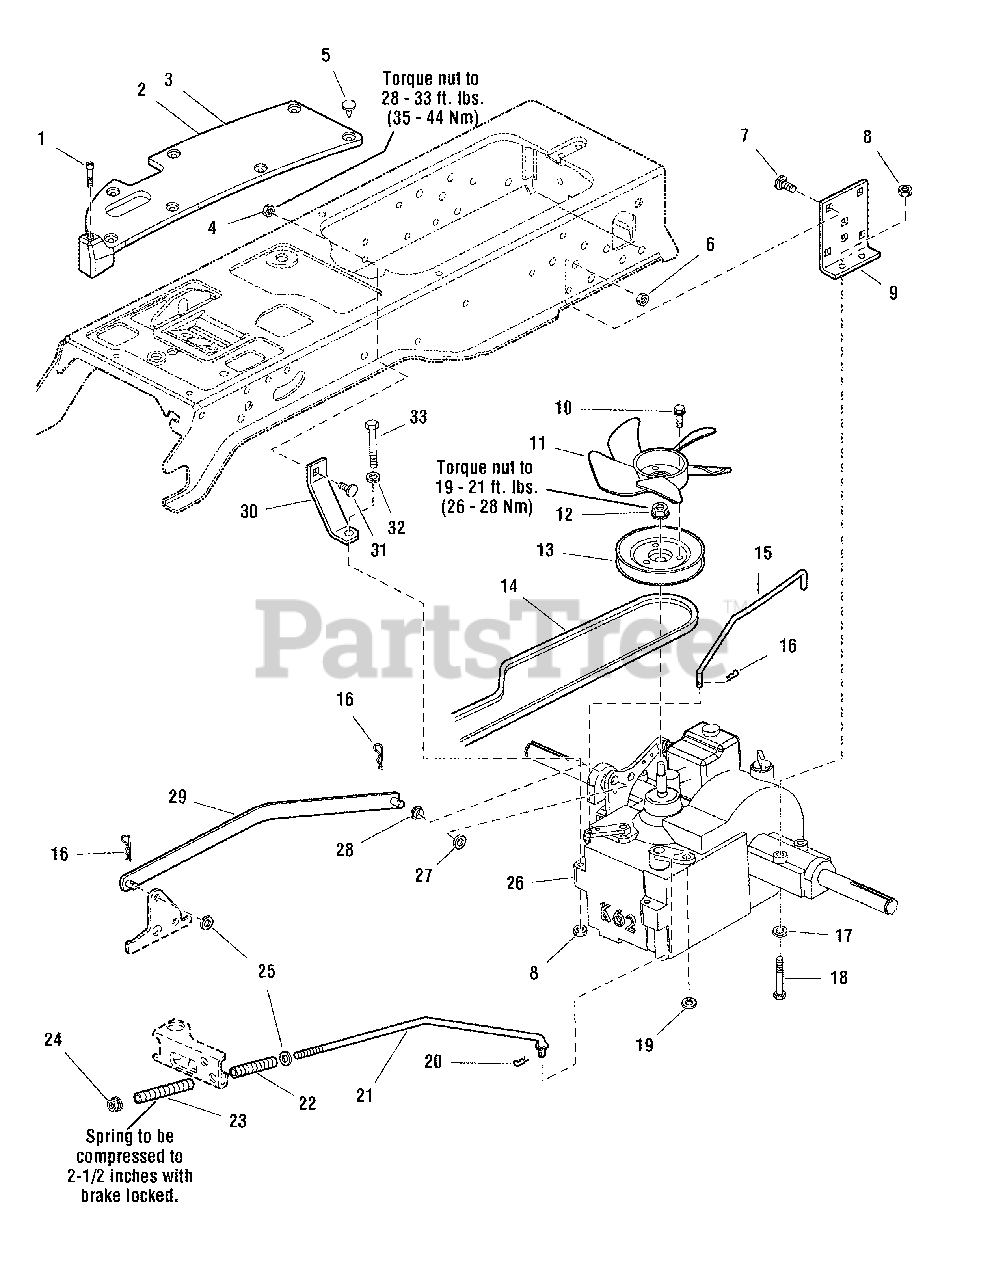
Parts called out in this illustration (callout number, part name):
1	CAPSCREW, Pan Head Trox Taptite, 1/4-20 x 1-1/4, Black
2	PAD, Footrest, LH, W/O Differential Lock
3	PAD, Footrest, RH
4	NUT, Hex KEPS, 5/16-18, Black
5	FASTENER, Panel
6	NUT, Hex KEPS, 3/8-16, Black
7	CARRIAGE BOLT, 3/8-16 x 1, Black
8	NUT, Hex Flange ESNA, 5/16-18, Black
9	SUPPORT, Transmission
10	CAPSCREW, Hex Head Taptite, 1/4-20 x 1-1/4, Black
11	FAN, 5 Blades, 3 Holes
12	NUT, Hex Flange Nylock, M10-1.50
13	PULLEY & HUB ASEMBLY
14	V-BELT, Drive
15	ROD, 1/4 x 18-5/16" Long
16	PIN, Quick
17	WASHER, 5/16, Black
18	CAPSCREW, Hex Head, 5/16-18 x 2-3/4, Black
19	WASHER, 15/32 x 15/16, Black
20	PIN, Cotter, Black
21	ROD, 3/8 x 15-15/16" Long
22	SPRING, Compression, 3-1/4" Long, Black
23	SPRING, Compression, 3-5/8" Long, Black
24	NUT, Hex Flange ESNA, 3/8-16, Black
25	WASHER, 3/8, Black
26	TRANSMISSION ASSEMBLY, K62, W/O Pulley
27	WASHER, 1/2, Black
29	CONTROL ARM ASSEMBLY
30	STRAP, Torque
31	CARRIAGE BOLT, 5/16-18 x 1, Black
32	WASHER, 5/16, Black
33	CAPSCREW, Hex Head, 5/16-18 x 2-1/2, Black
